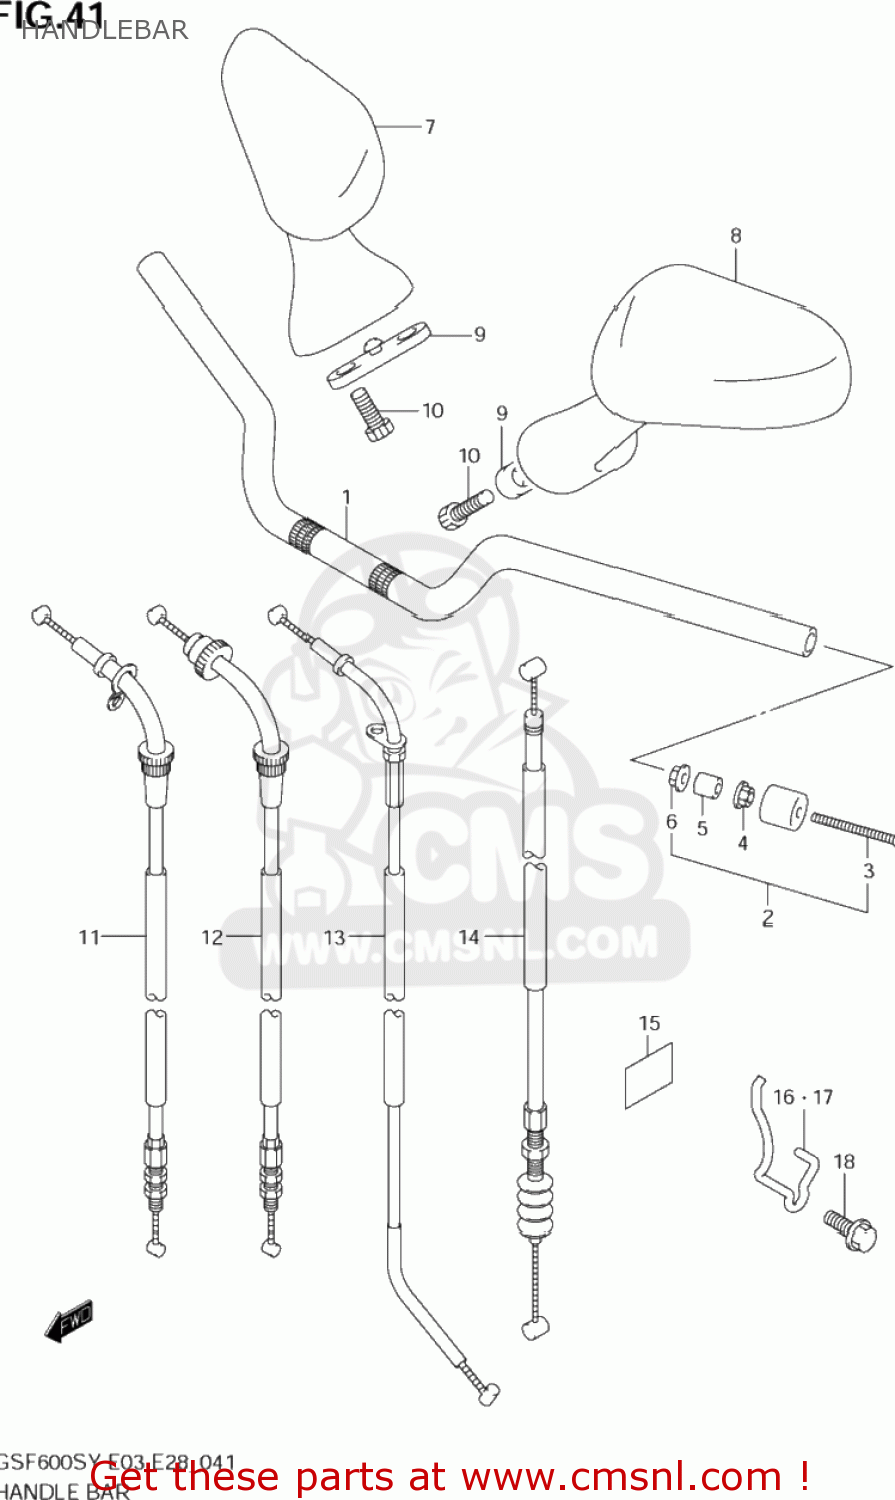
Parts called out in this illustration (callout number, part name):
1	HANDLEBAR
2	BALANCER SET,HANDLEBAR
3	SCREW
4	NUT
5	EXPANDER,HANDLE BALANCER
6	NUT
7	MIRROR ASSY,RR VIEW,R
8	MIRROR ASSY,RR VIEW,L
9	CUSHION,RR VIEW MIRRORR
10	BOLT
11	CABLE ASSY,THROTTLE NO.1
12	CABLE ASSY,THROTTLE NO.2
13	CABLE,STARTER
14	CABLE ASSY,CLUTCH
15	PROTECTOR,FRAME COVER FR
16	GUIDE,WIRING HARNESS
17	GUIDE,CABLE
18	BOLT
